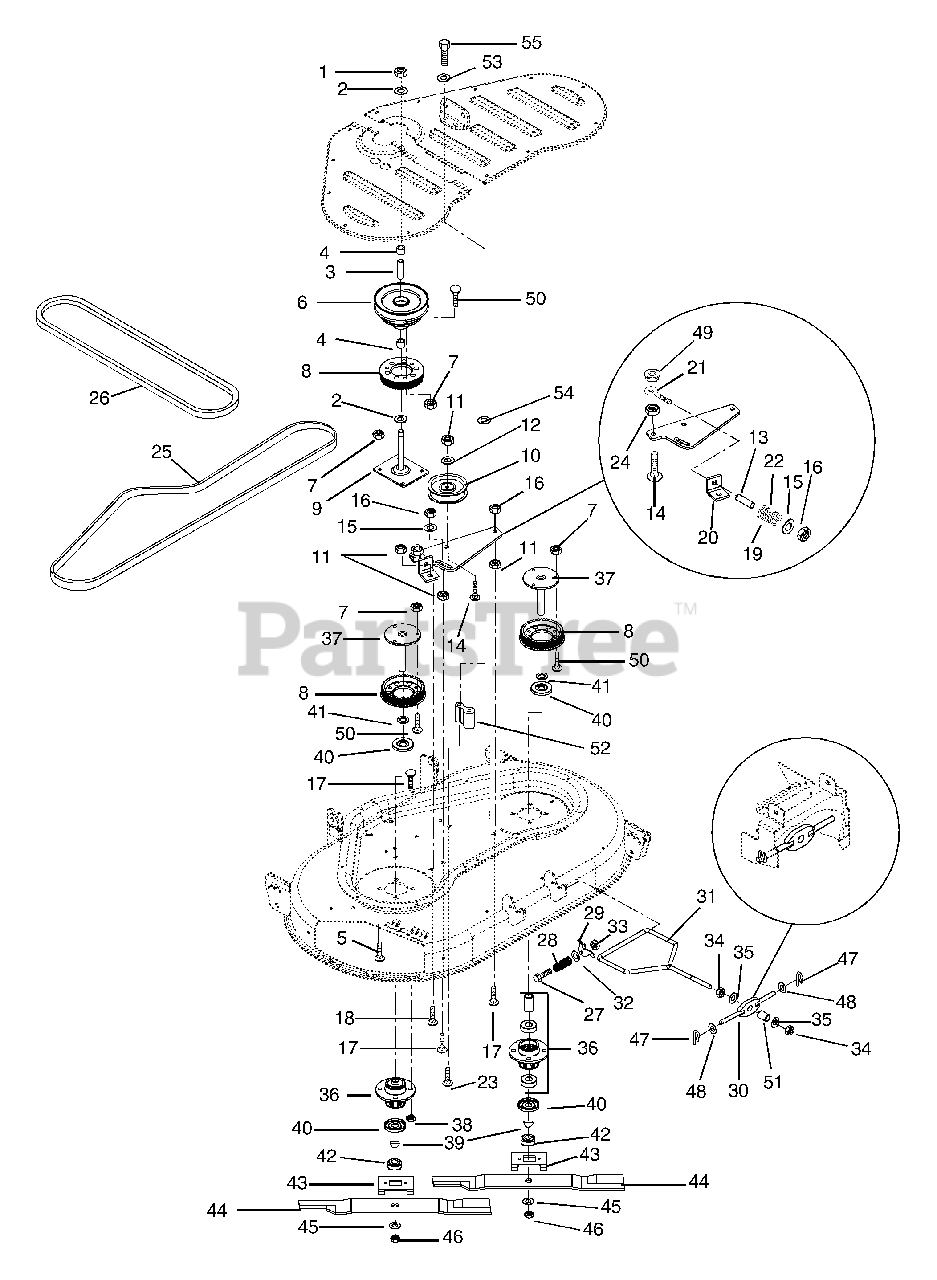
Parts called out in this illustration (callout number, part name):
1	@NUT-LK-NYL .625-18 YWZC
2	WSHR-FL-STL .630X1.005X.062 YZ
3	SPACER, .640X.88X3.634
4	BRG-BALL .625X1.375X.43
5	@BLT-RDHDSQNK .31-18X.75 G5YZ
6	JACKSHAFT (SIERRA)
7	@NUT-LK-CTR .31-18 YWZC
8	SPROCKET, DRIVE
9	WELDMENT, PLATE MOUNT (SIERRA)
10	IDLER, FLAT .377X4.0X.96W POLY
11	@NUT-LK-CTR-JAM .375-16 YWZC
12	@WSHR-FL-STL.406X.812X.065 YWZ
13	ARM, BELT ADJUSTMENT
14	@BLT-RDHDSQNK .38-16X1.75 G5YZ
15	@WSHR-FL-STL.438X1.00X.083 YWZ
16	@NUT-LK-CTR .38-16 YWZC
17	@BLT-RDHDSQNK .38-16X1.25 G5YZ
18	@BLT-RDHDSQNK .38-16X.75 G5YZ
19	SG-COMP .125X.781X1.250
20	BRACKET, BELT ADJUSTMENT
21	BLT-EYE .375-16X2.50 YWZC
22	SPACER .39X.50X.88
23	SCR.38-16X1.25 TRH TORX DR YZC
24	@NUT-LK-NYL .38-16 YWZC
25	COG-BELT X8M
26	V-BELT, HA-WRAPPED
27	@BLT-HEX .25-20X1.25 GR5 YWZC
28	SG-COMP .058X.68X.75
29	RETAINER, BRACE
30	WELDMENT, FRONT MOUNT
31	ROD, LINK
32	@WSHR-FL-STL.312X.734X.065 YWZ
33	@NUT-LK-NYL .250-20 YWZC
34	@NUT-LK-CTR .50-13 YWZC
35	@WSHR-FL-STL.563X1.38X.109YWZC
36	ASSEMBLY, SPINDLE HOUSING
37	WELDMENT, SPINDLE SHAFT
38	@NUT-LK-TOP-FLG .38-16 YWZC
39	KEY-WDRF .188X.625X.31 SAE9MOD
40	BEARING SLINGER
41	WSHR-FL-STL .755X1.25X.125 YZ
42	HUB, RETAINER
43	TRAY, BLADE
44	BLADE, 22" LOW LIFT - CE
45	@WSHR-LK .75X.188 REG YWZC
46	NUT-JAM .75-10 YWZC
47	CLIP, SPRING
48	@WSHR-FL-STL.531X1.06X.095YWZC
49	NUT-LK-CTR-FLG .38-16 YWZC
50	@BLT-RDHDSQNK .31-18X1.00 G5YZ
51	BSHG-SLV .50X.74X.53
52	SUPPORT, LIFT BRACKET
53	@WSHR-LK .38X.094 REG YWZC
54	@WSHR-FL-STL.38X.875X.083 YWZC
55	@BLT-HEX .38-16X.75 GR5 YWZC
